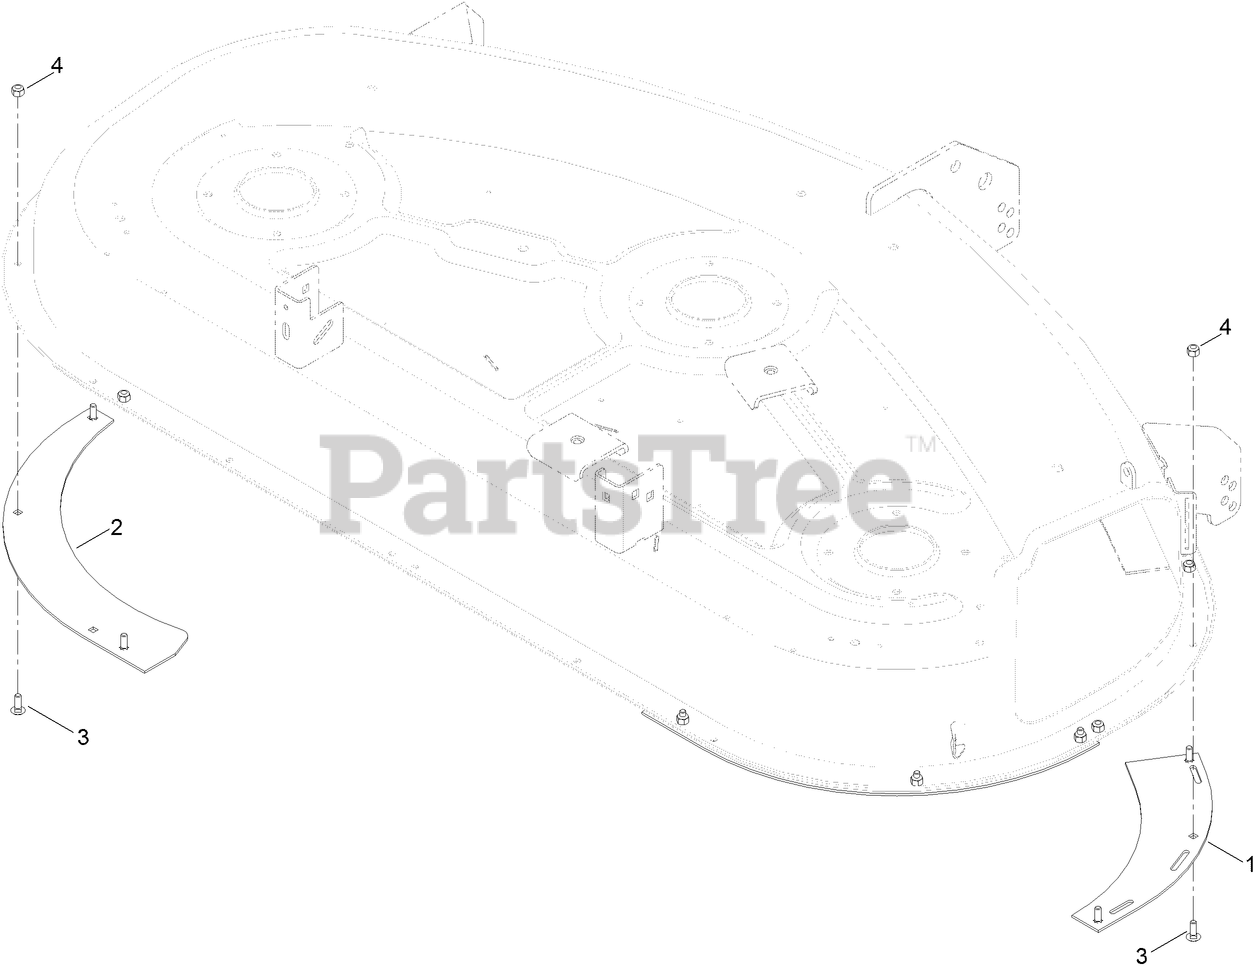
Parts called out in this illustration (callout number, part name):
1	BAFFLE-END
2	BAFLE-BLOWOUT, REAR
3	BOLT-CARR
4	NUT-LOCK, NI
